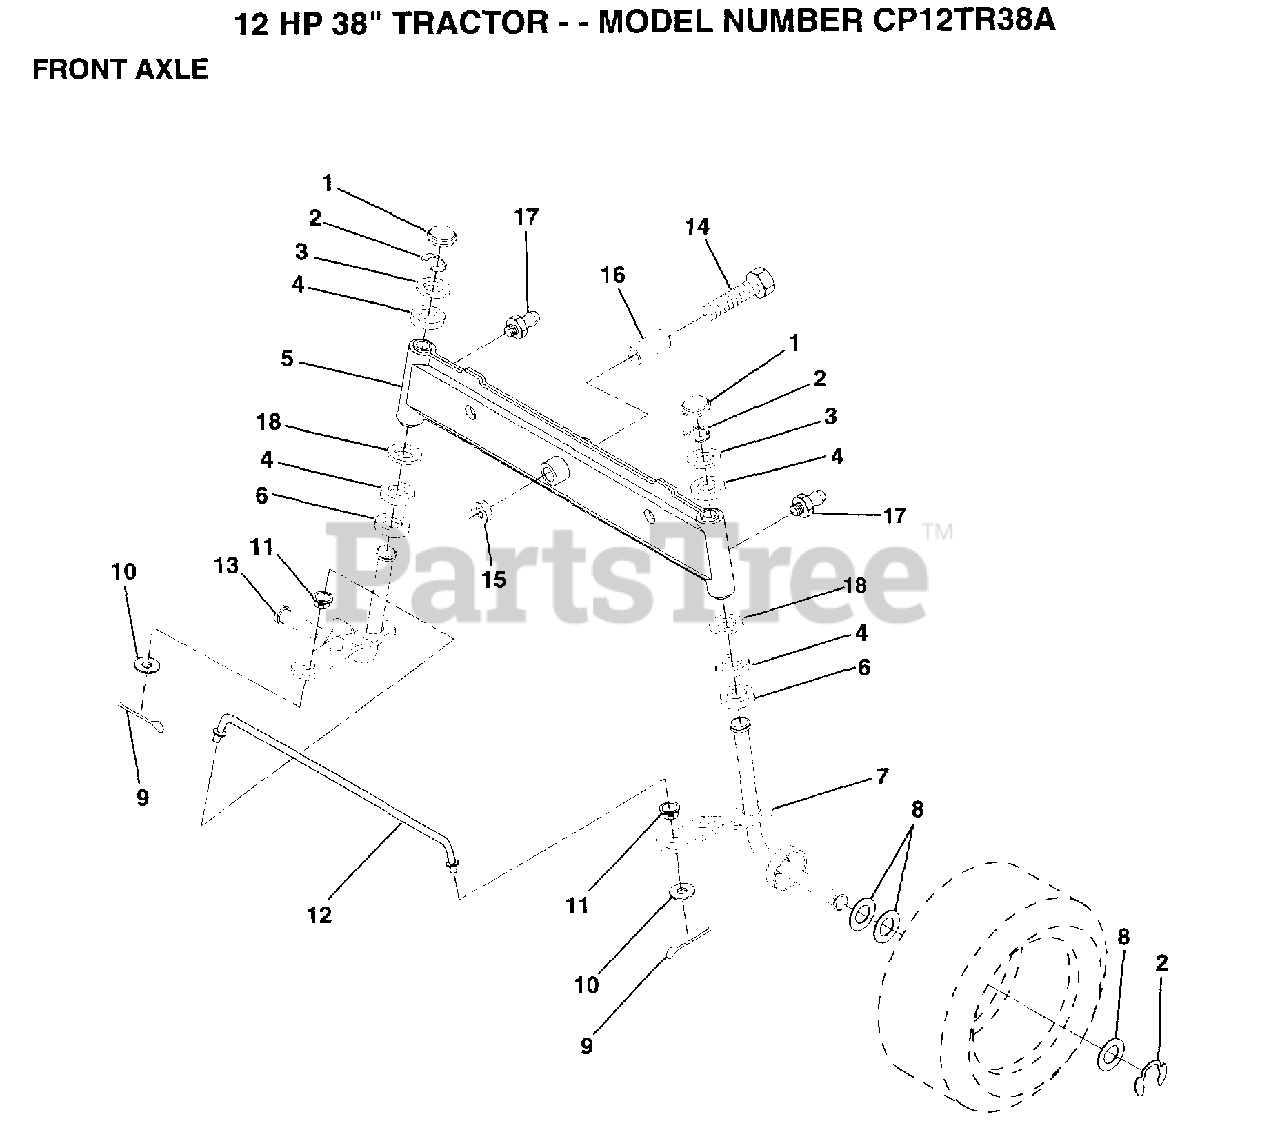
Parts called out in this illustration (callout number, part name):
1	CAP
2	RING
3	WASHER
4	COL. SRTG. BEAR.
5	AXLE ASM FRONT
6	WASHER .T
7	SPINDLE ASM RH
8	WASHER
9	COTTER PIN
10	WASHER
11	BUSHING.DRAGLINK
12	TIE ROD
13	SPINDLE ASM LH
14	BOLT HEX 5/8-11
15	"NUT-LOC,FLANGE LT"
16	BEARING
17	ZERK M
18	WASHER
